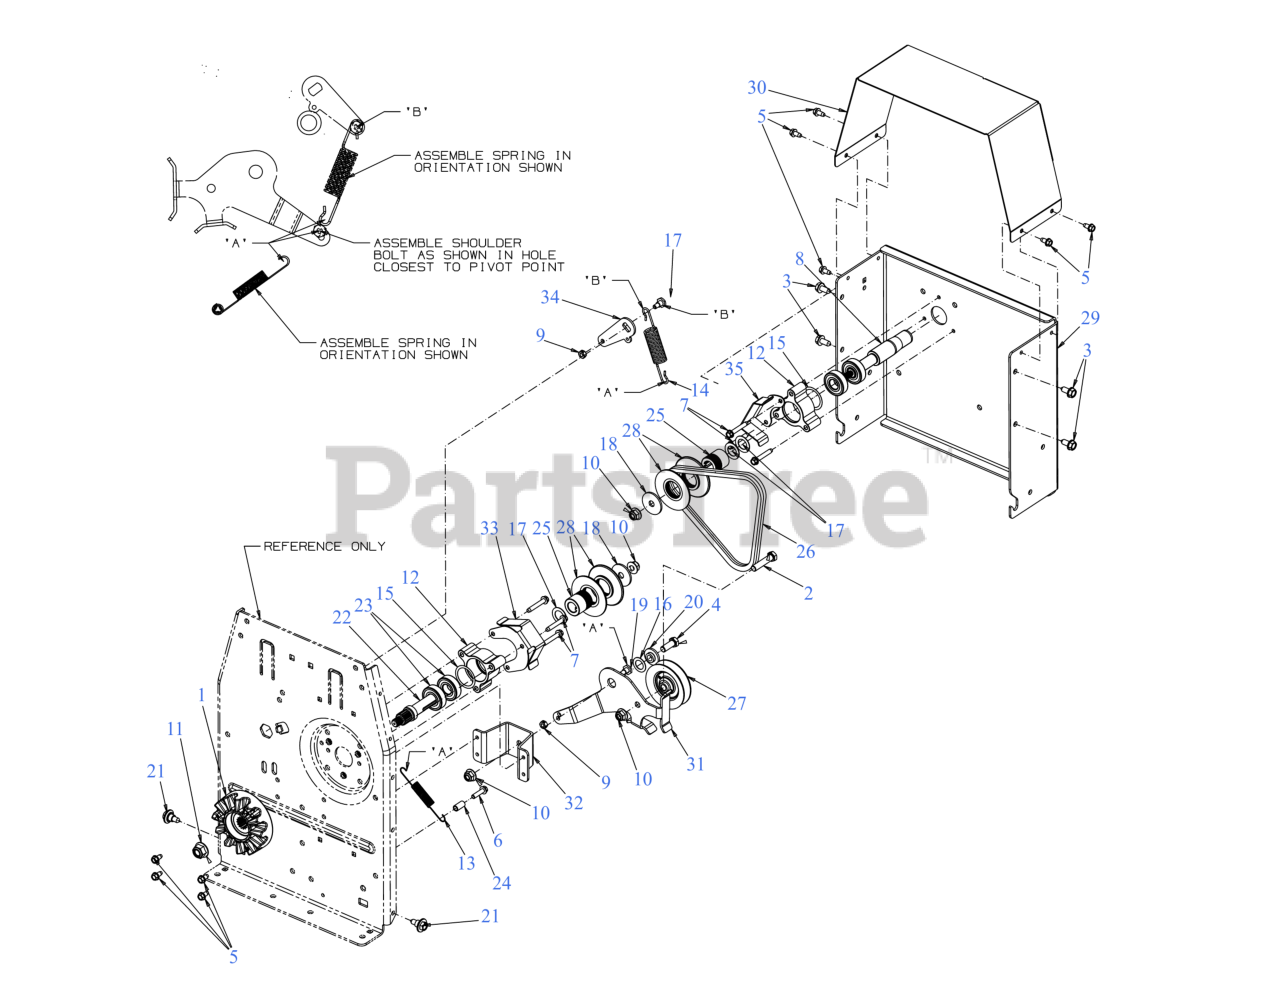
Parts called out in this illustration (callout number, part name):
1	DOG CLUTCH ASSEMBLY
2	HEX SCREW 3/8-16 x 1.75 GR5
3	SCREW 5/16-18 x .750
4	SCREW 3/8-16 x 1 GR5
5	SCREW 1/4-20 X.500
6	SCREW 1/4-20 x 1.00
7	SCREW 1/4-20 X1.625
8	SPINDLE SHAFT
9	HEX LOCK NUT
12	BEARING CUP
13	EXTENSION SPRING
14	EXTENSION SPRING.85 ODX 5.026
15	SHIM WASHER
16	THRUST WASHER
17	THRUST WASHER
18	FLAT WASHER .406X1.5X11
19	SHOULDER SCREW .340
20	SHOULDER SPACER
21	SHOULDER SCREW .43X.29X5/16-18 TT
22	DRIVE SPINDLE
23	BALL BEARING
24	SPACER .260 x .375 x .75
25	SPACER-.670ID x 1.185
26	V-BELT 4L:24.82
27	V-IDLER PULLEY A x 3.06 OD
28	HALF PULLEY
31	IDLER BRACKET
34	ENGAGEMENT CABLE BRACKET
